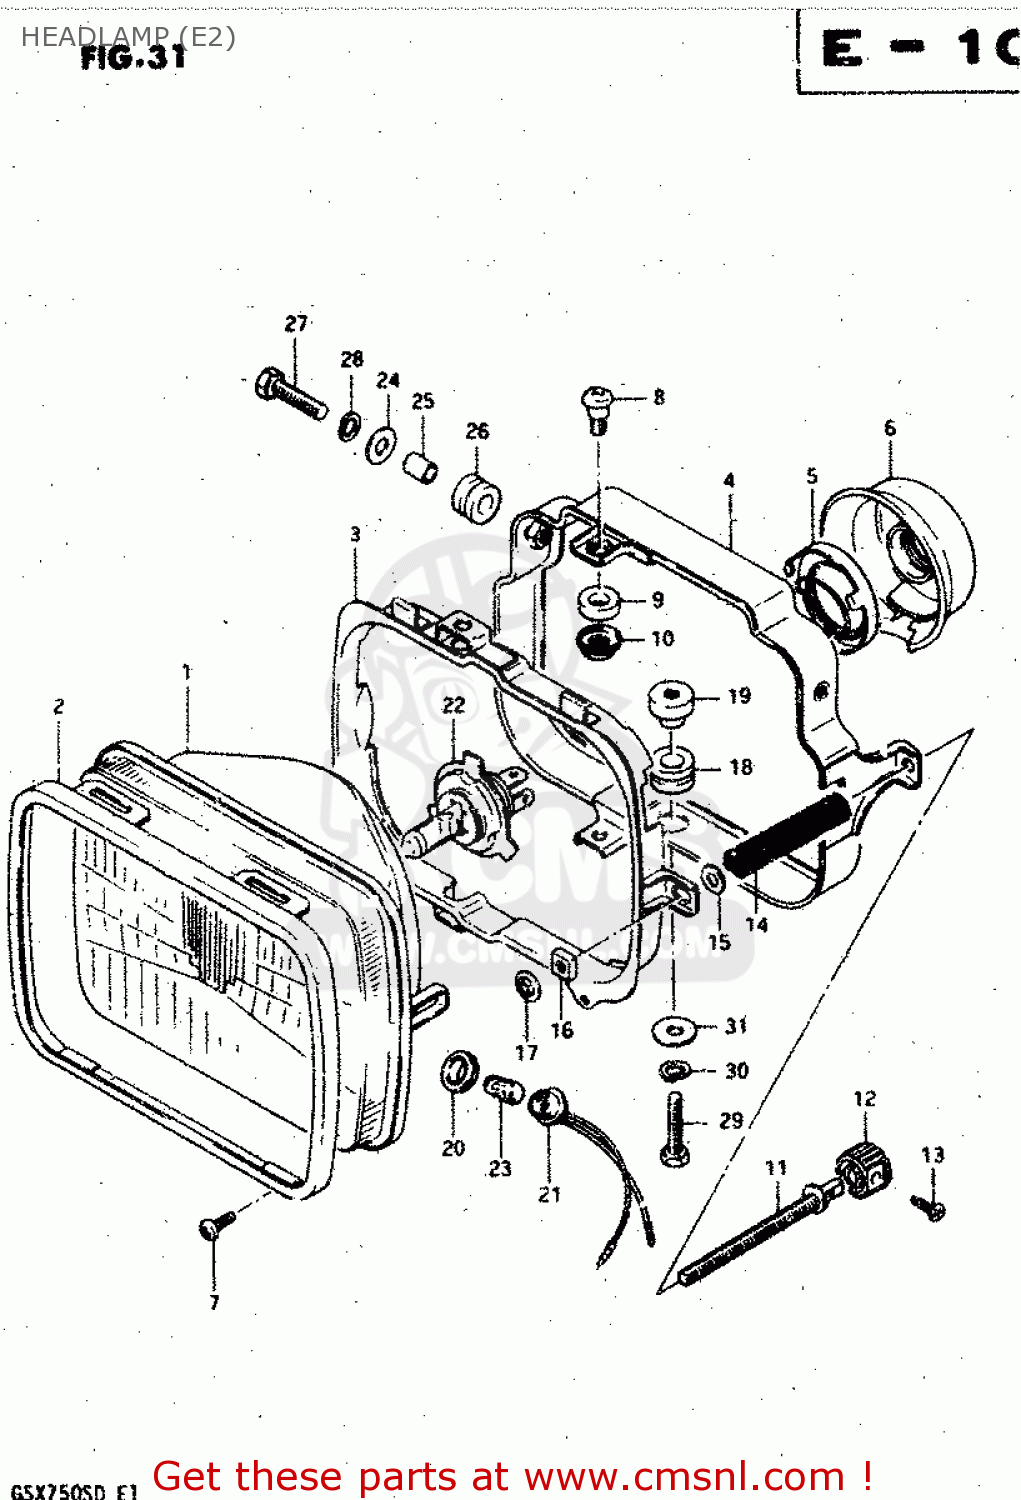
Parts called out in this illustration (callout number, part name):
1	UNIT
2	RETAINER
3	RING,MOUNTING
4	HOUSING
5	HOLDER
6	COVER,HEADLAMP SOCKET
7	SCREW
8	SCREW
9	SPACER
10	NUT,ADJUSTING
11	SCREW,ADJUSTING
12	KNOB,ADJUSTER
13	SCREW
14	SPRING
15	WASHER
16	NUT
17	NUT,HEADLAMP ADJUSTER
18	CUSHION
19	NUT
20	JOINT,RUBBER
21	SOCKET
22	BULB(12V60/55W,H4)
23	BULB(12V4W)
24	WASHER
25	SPACER (6.1X8X9.5)
26	CUSHION
27	BOLT
28	LOCK WASHER
29	SCREW(6X20)
30	LOCK WASHER
31	WASHER
